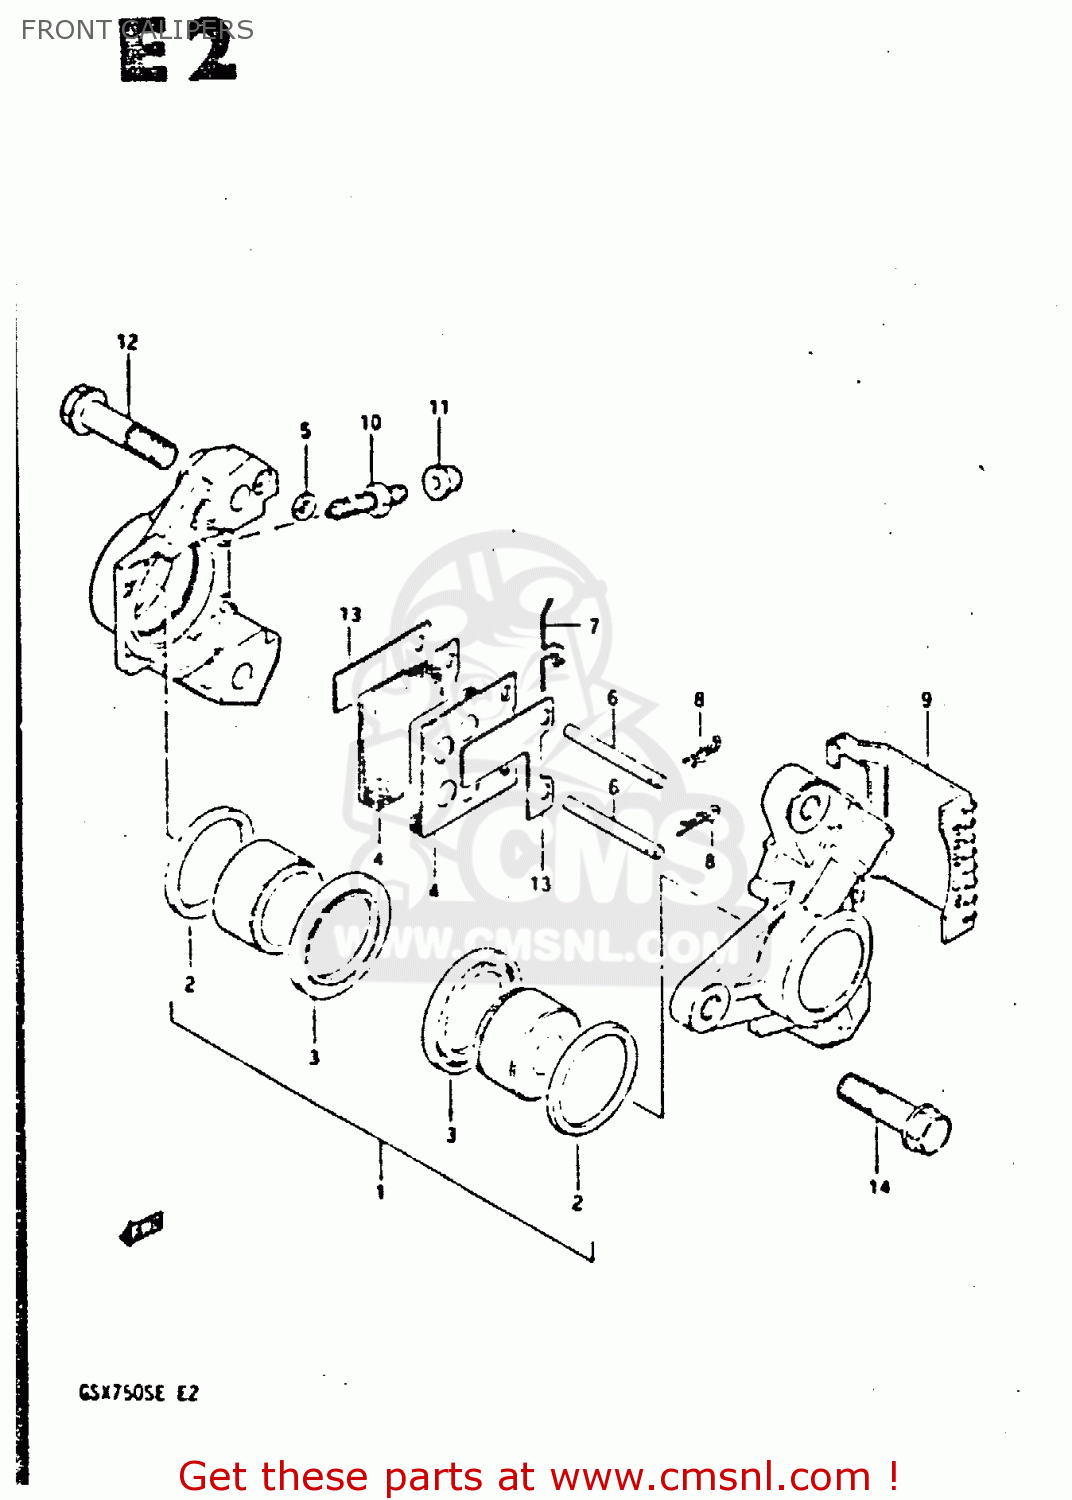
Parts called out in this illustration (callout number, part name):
1	PISTON SET
2	SEAL,PISTON
3	BOOT
4	PAD
5	SEAL,JOINT
6	PIN,PAD
7	SPRING
8	CLIP,PAD PIN
9	COVER,CALIPER
10	BLEEDER
11	CAP,BREATHER
12	BOLT,HOUSING
13	SHIM
14	BOLT 10X40
